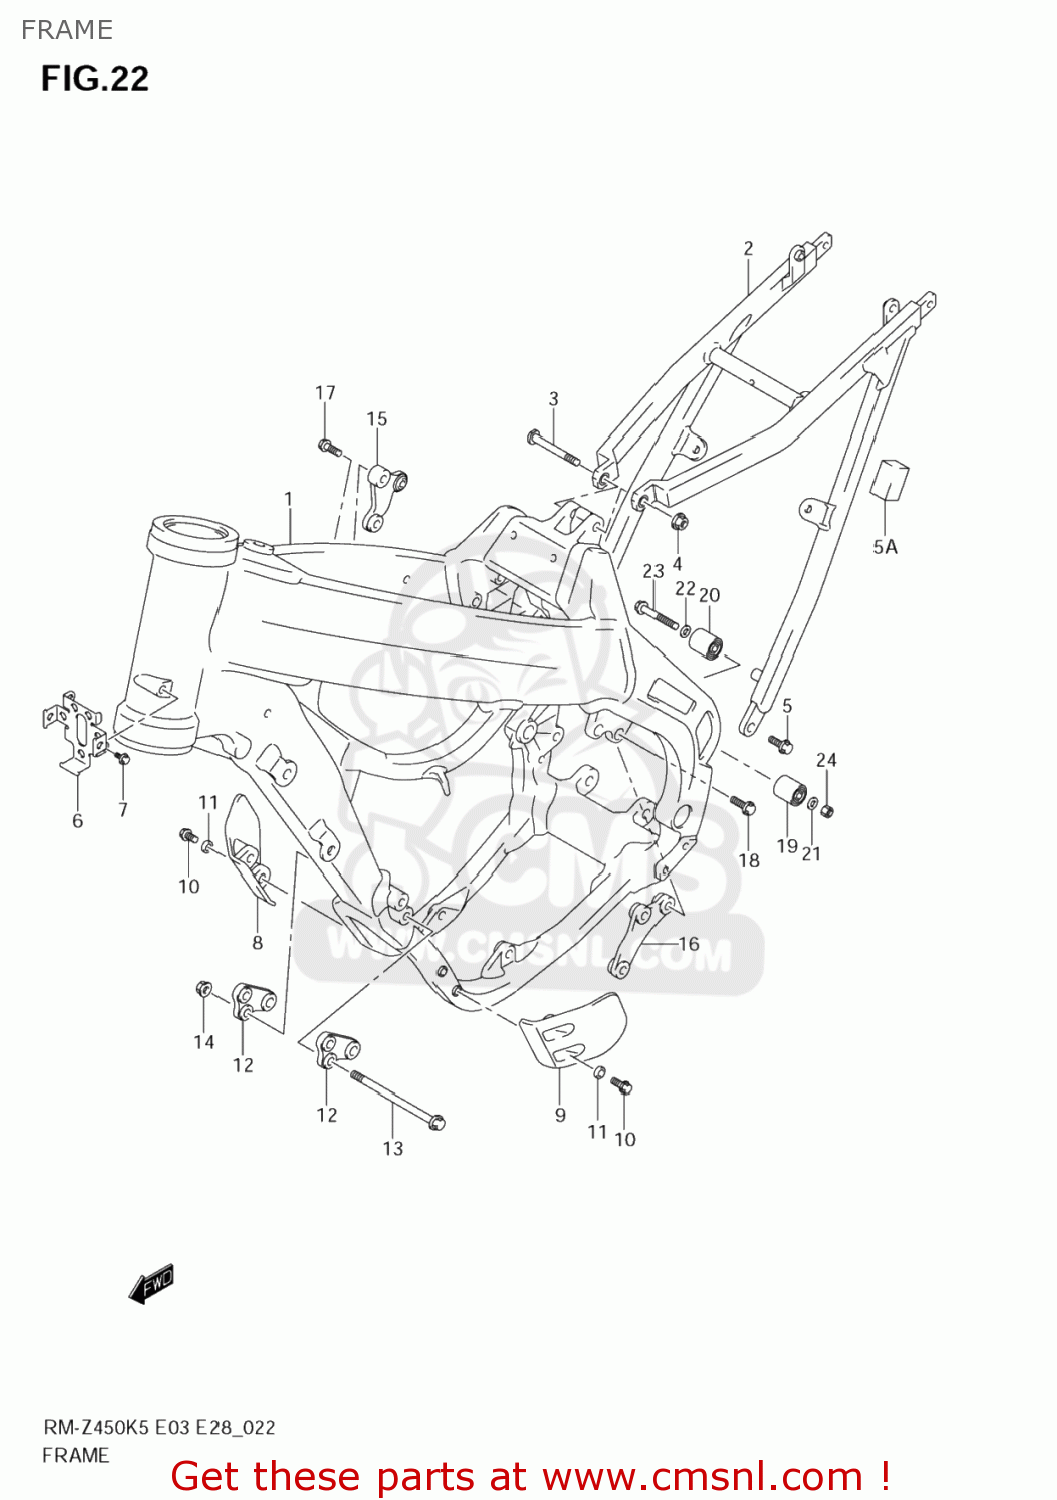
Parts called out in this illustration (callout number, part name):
1	FRAME
2	RAIL,SEAT
3	BOLT
4	NUT
5	BOLT(8X19.5)
5A	CUSHION,SEAT RAIL
6	BRACKET,CDI
7	BOLT(6X10)
8	PROTECTOR,FR,R
9	PROTECTOR,FR,L
10	BOLT(6X16)
11	WASHER(6.5X16X1.2)
12	BRACKET,ENGINE MOUNTING FR
13	BOLT(8X125)
14	NUT
15	BRACKET,ENG MT
16	BRACKET,ENGINE MOUNTING UPR,L
17	BOLT(8X21)
18	BOLT(8X16)
19	ROLLER,CHAIN
20	ROLLER,CHAIN
21	SHIM(8X12X1)
22	SHIM(8X16X1)
23	BOLT(8X45)
24	NUT
